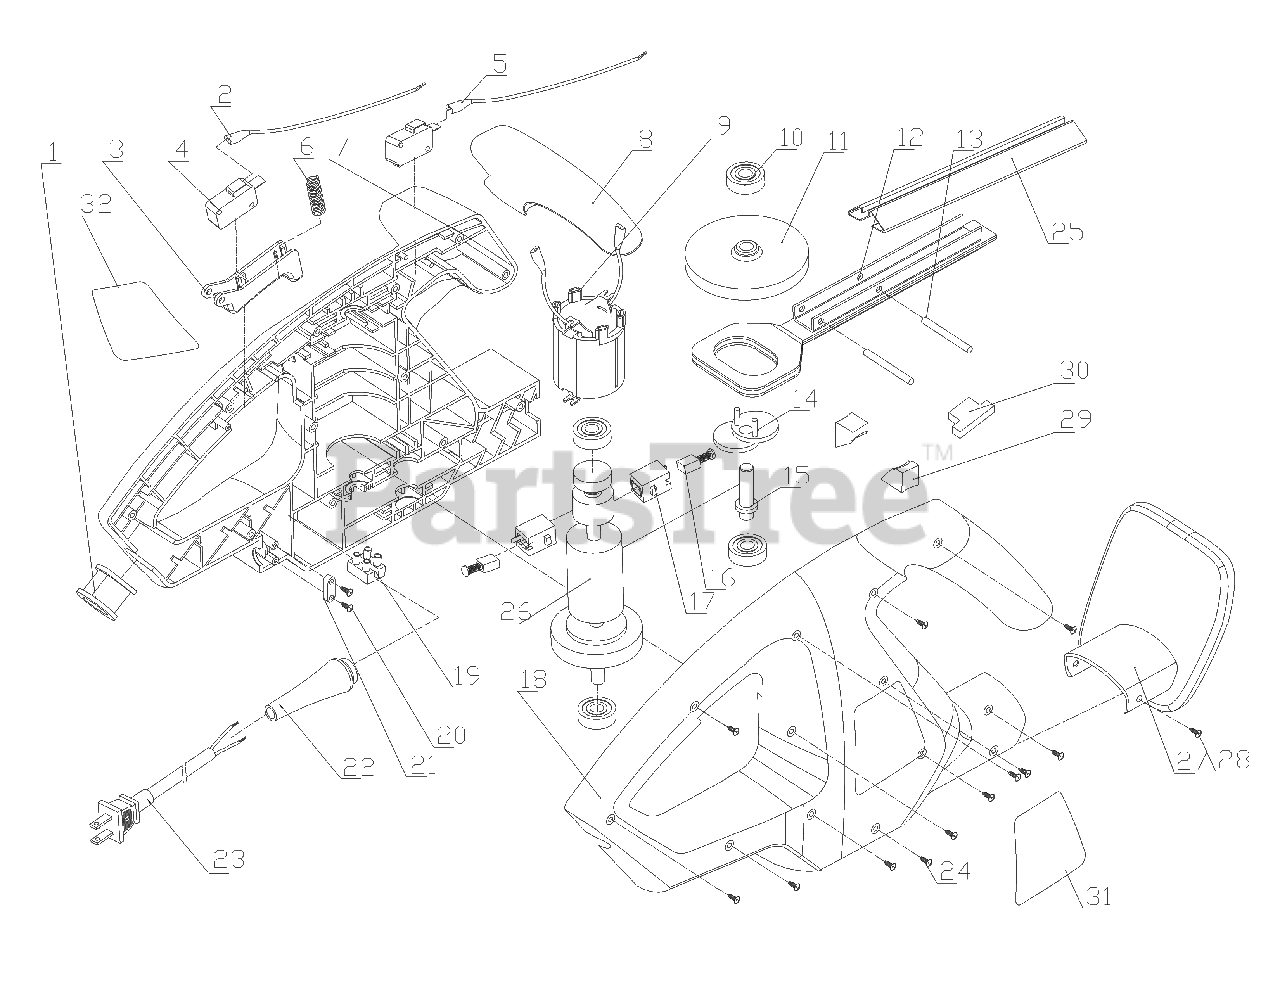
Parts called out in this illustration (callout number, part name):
1	Tube
2	Wire
3	Trigger
4	SWITCH
5	WIRE
6	SPRING
7	HOUSING (L)
8	TRIGGER
9	FIELD ASS'Y
10	BEARING
11	GEAR
12	18" BLADE
13	PIN
14	ECCENTRIC SHAFT
15	OUTPUT SHAFT
16	BRUSH
17	BRUSH HOLDER
18	HOUSING (R)
19	TERMINAL BLOCK
20	SCREW
21	STRAIN RELIEF
22	CORD GUARD
23	POWER CORD
24	SCREW
25	BLADE COVER
26	ARMATURE
27	COVER
28	SCREW
29	GASKET
30	GASKET
31	LABEL (R)
32	LABEL (L)
